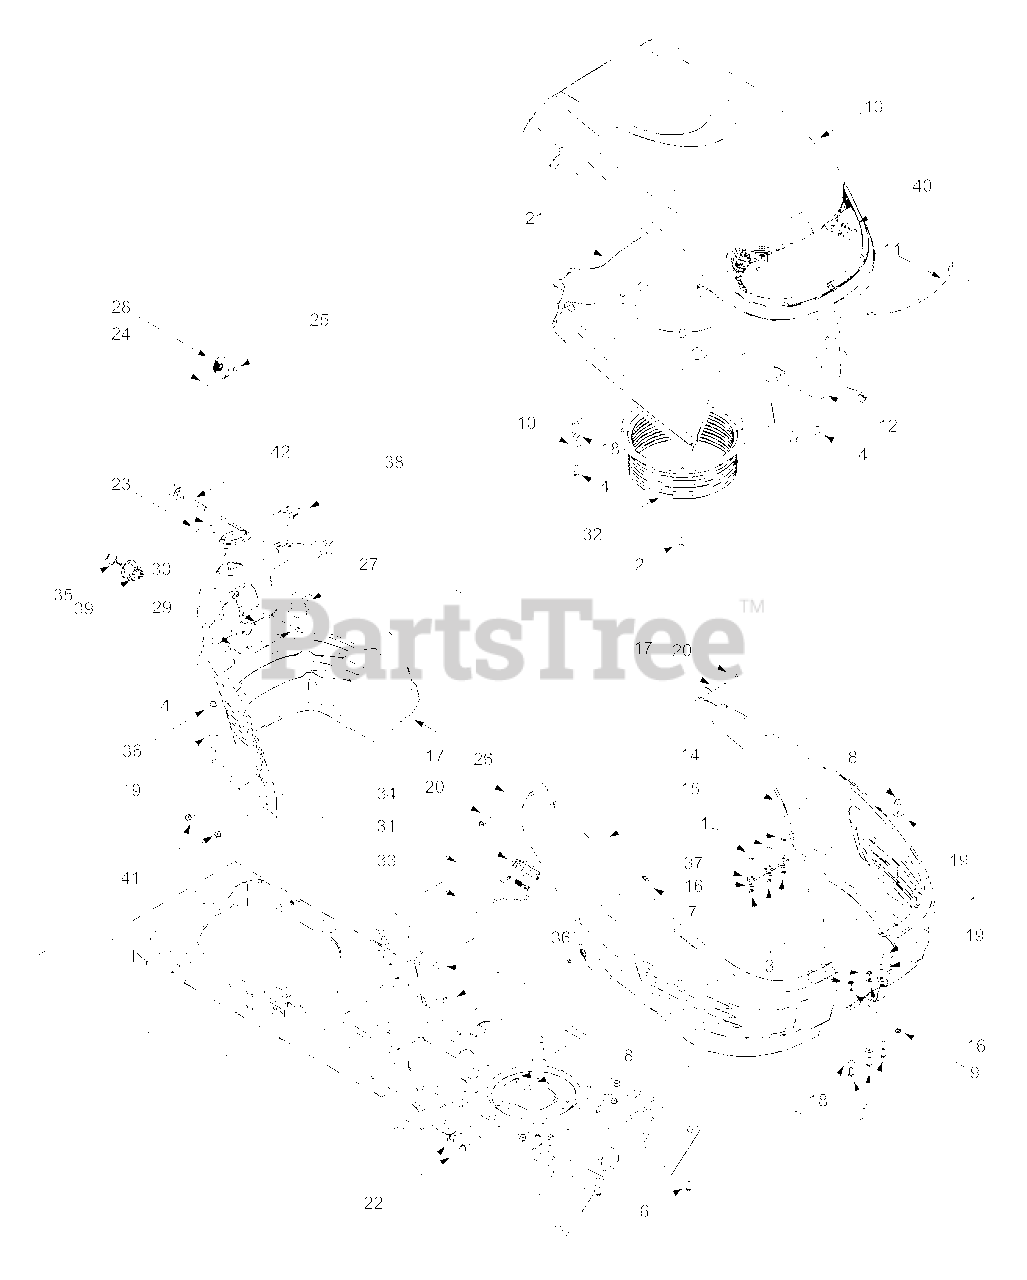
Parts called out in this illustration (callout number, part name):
1	Hex Cap Screw, 1/4-20 x .75
2	Self-tapping Screw, 1/4-20 x .5
3	Hex Nut, 1/4-20
4	Self-tapping Screw, 1/4-15 x .75
6	Hex Cap Screw, 5/16-18 x 1.0
7	U-type Speed Nut, 1/4-20
8	Flange Lock Nut, 5/16-18
10	Hood Latch Rod
11	Head Light Lens
14	LH Side Panel
15	RH Side Panel
16	Lock Washer, 1/4
17	Flat Washer, .283 x .75 x .030
18	Flat Washer, .28 x .74 x .063
19	Flat Washer, .349 x 1.0 x .063
20	Self-tapping Screw, 1/4-20 x 1.25
22	Self-tapping Screw, 5/16-18 x .625
23	Torx Self-tapping Screw, 1/4-14 x .625
24	Torx Screw, #8-32 x .375
25	Hex Nut, 8-32
26	Dash Panel, 4-style (LT-1650)
27	Parking Brake Button
28	Throttle Control Lever
29	Cruise Control Button
30	Brake/Cruise Pivot Rod
33	Fuel Tank, 3-gallon
34	Fuel Cap
35	Ignition Key w/ plastic cover
36	Self-tapping Screw, 5/16-18 x .75
39	Ignition Switch
40	Headlight Assembly
41	Self-tapping Screw, 5/16-18 x .75
42	Choke Control
